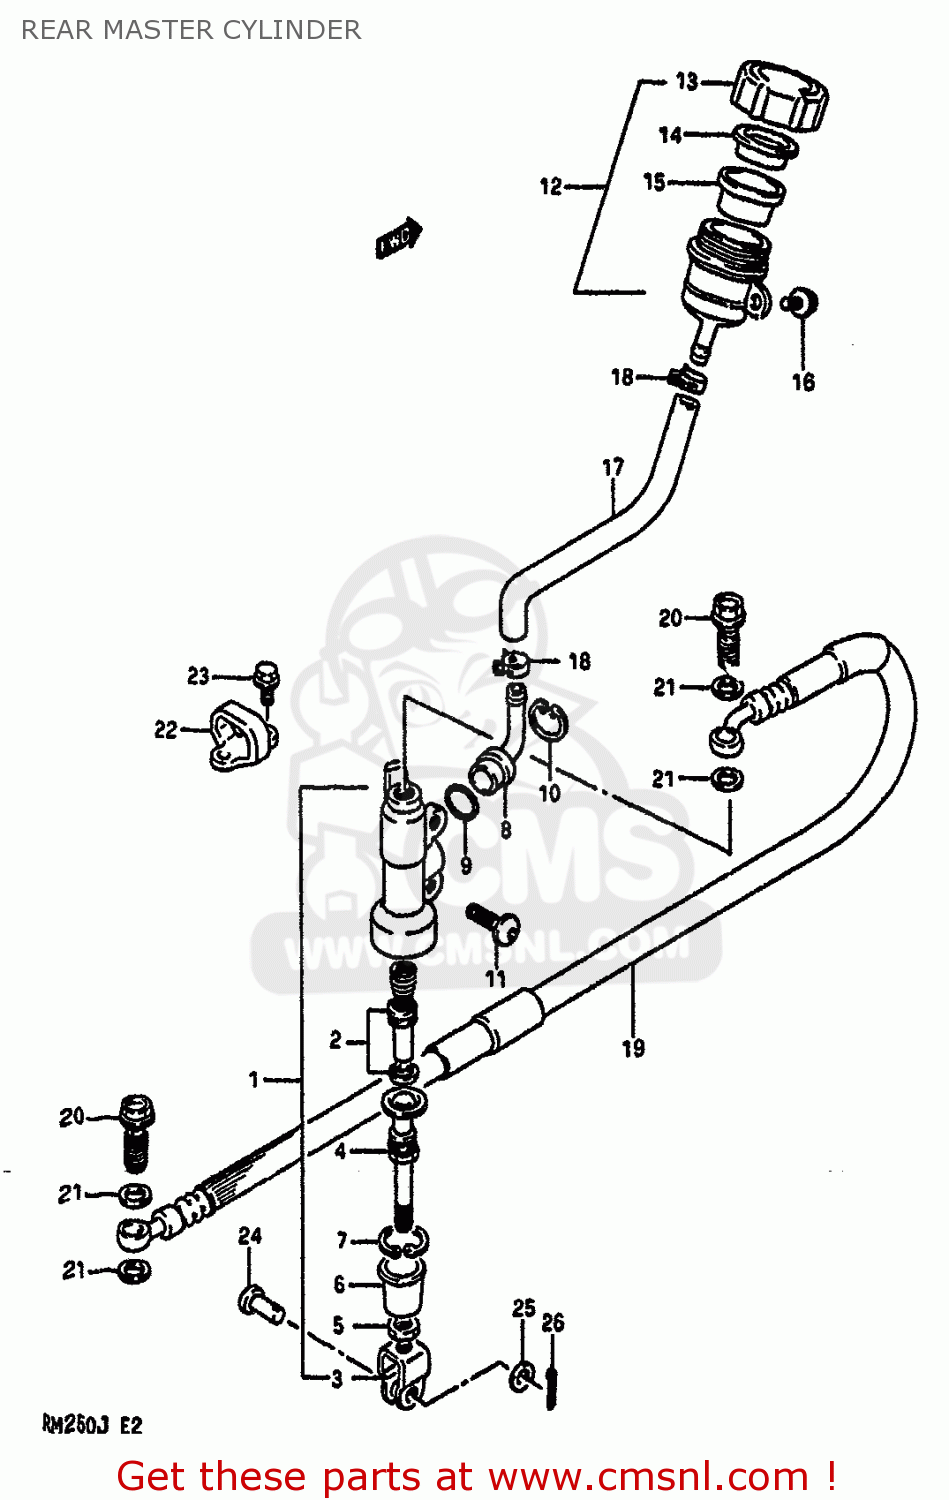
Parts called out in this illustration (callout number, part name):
1	CYLINDER ASSEMBLY,REAR MASTER
2	PISTON/CUP SET
3	YOKE
4	ROD,PUSH
5	NUT
6	BOOT
7	CIRCLIP
8	CONNECTOR
9	O RING
10	CIRCLIP
11	BOLT(6X18)
12	TANK ASSEMBLY,RESERVOIR
13	CAP
14	PLATE
15	DIAPHRAGM
16	BOLT
17	HOSE,RESERVOIR TANK
18	CLAMP,RESERVOIR HOSE
19	HOSE,REAR BRAKE
20	BOLT UNION
21	WASHER(10X15X1.5)
22	GUIDE,RR BRAKE HOSE
23	SCREW(5X10)
24	PIN(8X20)
25	WASHER(8.5X13X1.6)
26	PIN
